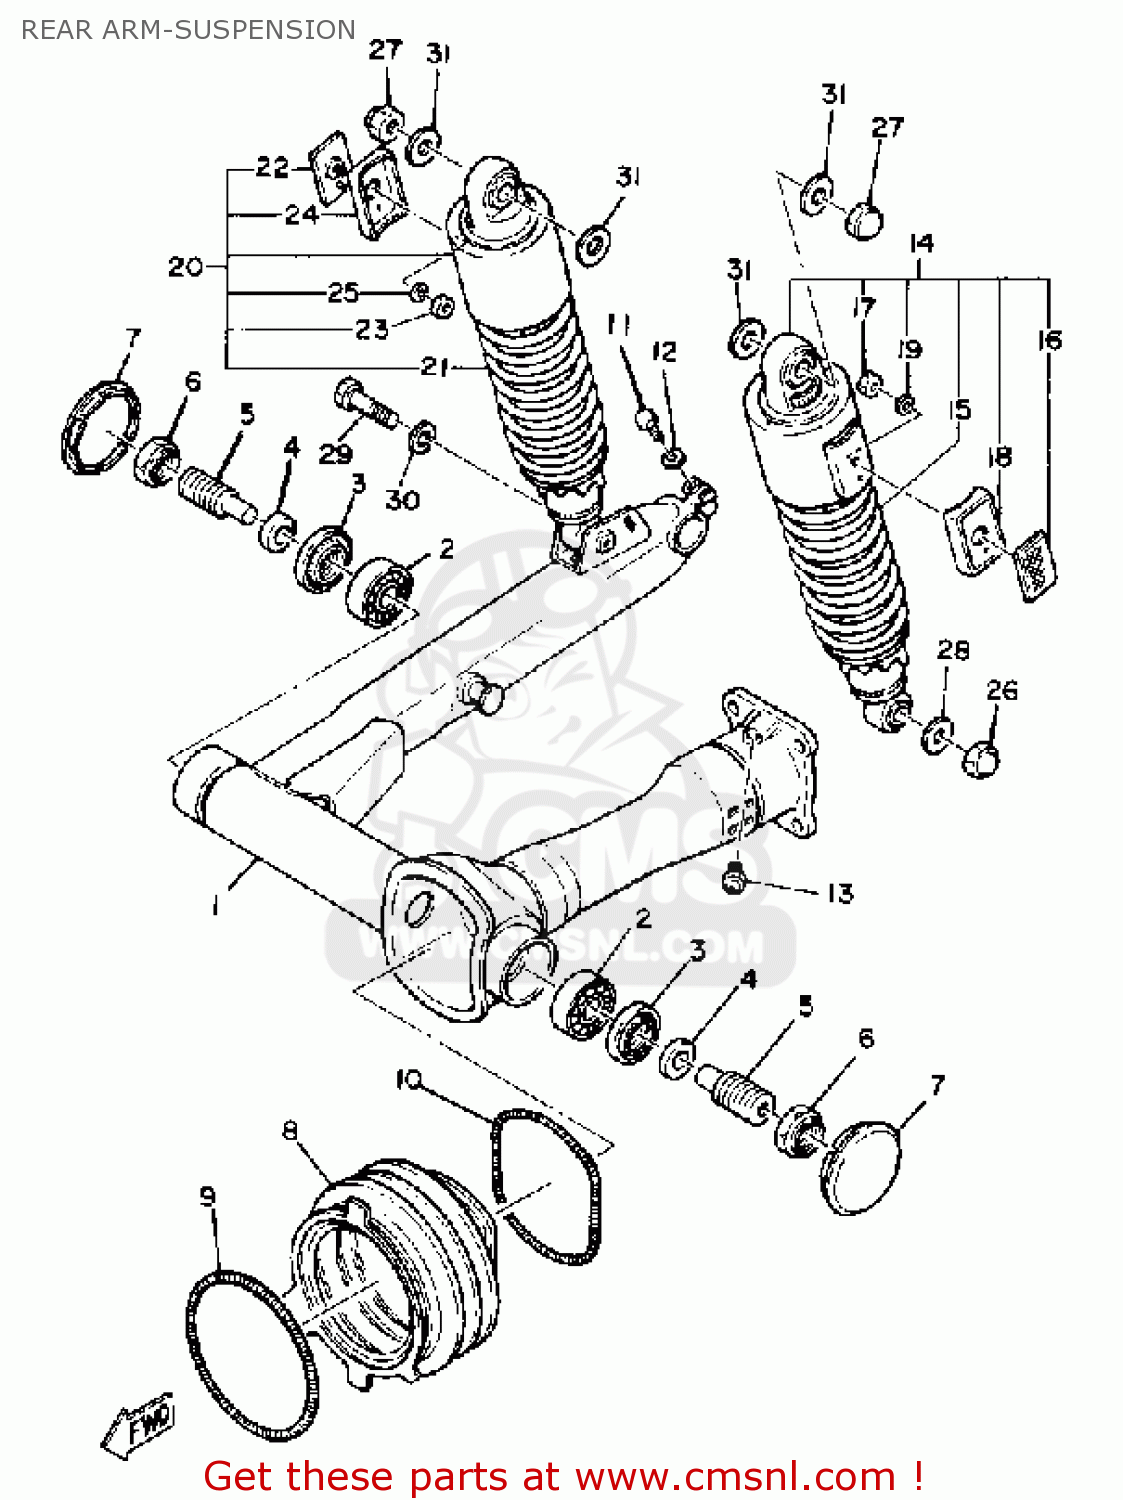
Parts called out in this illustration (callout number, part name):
1	REAR ARM COMP.
2	BRG,CYL-CAL ROLLER 74G KY
3	OIL SEAL (25X40X5-101)
4	COLLAR (1J7)
5	SHAFT, PIVOT
6	NUT, PIVOT SHAFT
7	COVER
8	BOOT, RUBBER
9	SPRING, TENSION (1J7)
10	SPRING, TENSION (1J7)
11	BOLT
12	WASHER,SPRING
13	NIPPLE, GREASE(6A1)
14	SHOCK ABSORBER ASSEMBLY REAR (LH)
15	SPRING, HEAVY DUTY
16	REAR REFLECTOR ASSY
17	NUT, HEXAGON (663)
18	BASE, REFLECTOR REAR
19	YBS66-5 WASHER, PLAIN
20	SHOCK ABSORBER ASSEMBLY, REAR (RH)
21	SPRING
22	REAR REFLECTOR ASSY
23	NUT, HEXAGON (663)
24	BASE, REFLECTOR REAR
25	YBS66-5 WASHER, PLAIN
26	NUT, CAP
27	NUT, CAP (371)
28	WASHER, PLATE (2J2)
29	BOLT (1J7)
30	YBS67-10 WASHER, SPRING
31	WASHER, PLATE (3J6)
